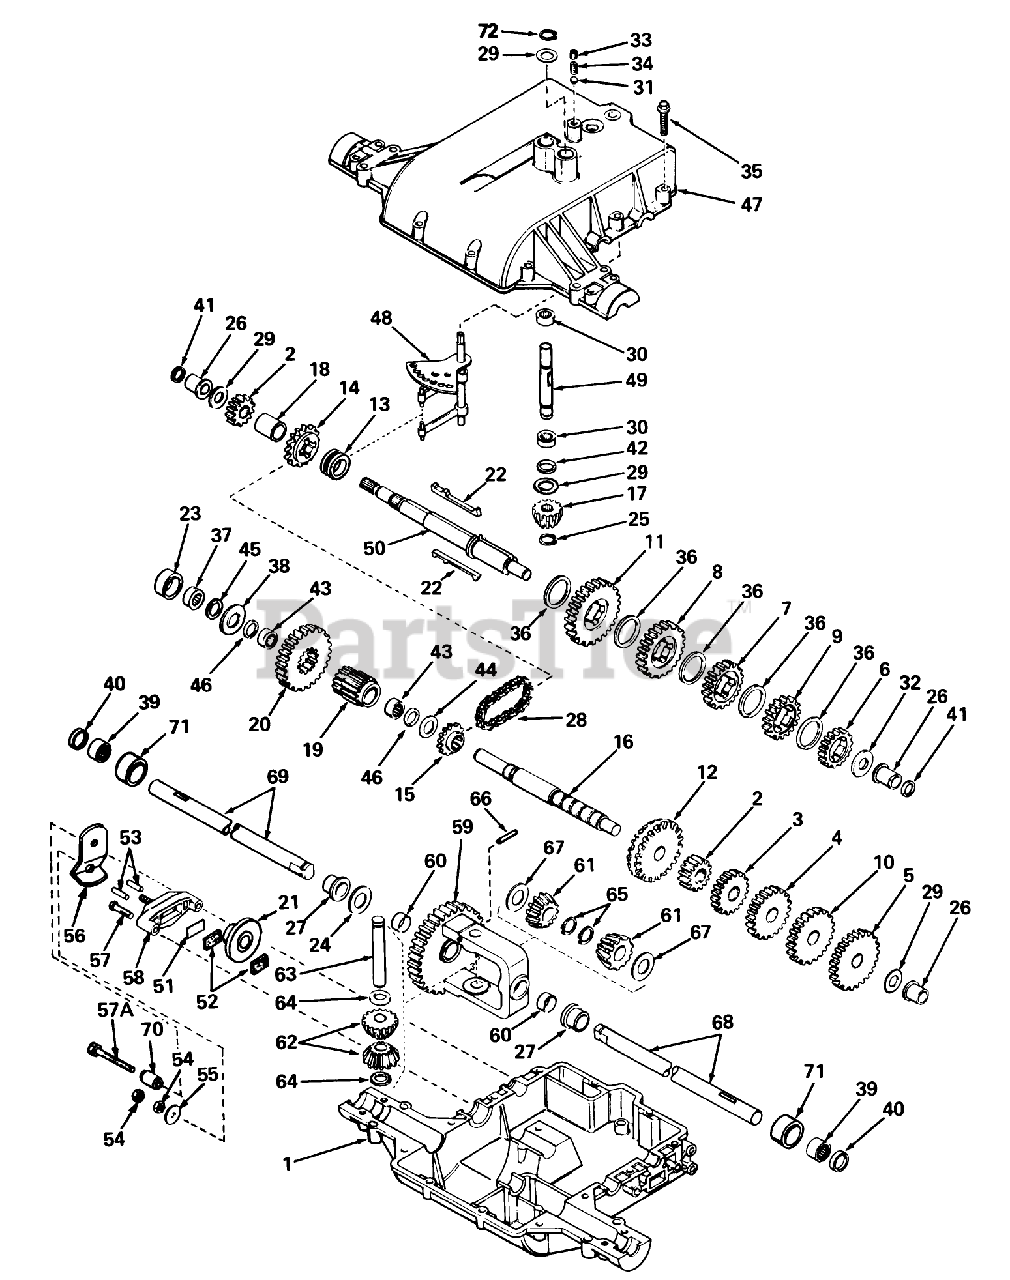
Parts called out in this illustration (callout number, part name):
1	Case, Transaxle
2	Gear-Spur 15 Teeth
3	Gear, Spur (20 teeth)
4	Gear, Spur (25 teeth)
5	Gear, Spur (30 teeth)
6	Gear-Spur 20 teeth
7	Gear, Spur (25 teeth)
8	Gear, Spur (30 teeth)
9	ASpur Gear (22 Teeth)
10	Gear, Spur (28 teeth)
11	Gear-Spur, 35 Teeth
12	Gear, Bevel (42 teeth)
13	Collar-Shift
14	Sprocket-18 Teeth
15	Sprocket-9 Teeth
16	Shaft-Counter
17	Bevel Pinion-Input
18	Spacer
19	Pinion-Output
20	Gear-Output
23	Spacer
24	Washer
25	Ring-Retainer
26	Bushing, Flanged
27	Bushing, Flanged
28	Chain-Roller #41
29	Washer
30	Bearing-Needle
31	Ball-Steel
32	Washer
33	Screw-Set
34	Spring
35	Ring Set (.020 O S)
36	Washer
37	Bearing-Needle
38	Washer-Flat
39	Bearing-Cartridge
40	Seal Oil
41	Ring-Square Cut
42	O Ring
43	Bearing-Needle
44	Washer-Flat
45	Ring-Square Cut
46	Ring-Square Cut
47	Cover-Transaxle
48	Rod Fork Assembly
49	Shaft, Input
50	Shaft, Brake
51	Brake Pad Plate
52	Brake Pad
53	Dowel Pin
54	Locknut
55	Washer
56	Lever-Brake
57	Ring Set (.020 O S)
57A	Screw-Hex. Flange
58	Holder-Brake Pad
59	Gear Assy., Differential (Incl. 2 of No. 60)
60	Bushing
61	Bevel Gear
62	Gear Pinion
63	Drive Pin
64	Thrust Washer
65	Ring-Snap
66	Pin-Roll
67	Washer
68	Axle (14 7/8" long)
69	Axle (13" long)
70	Spacer
71	Sleeve
72	Ring-Snap
